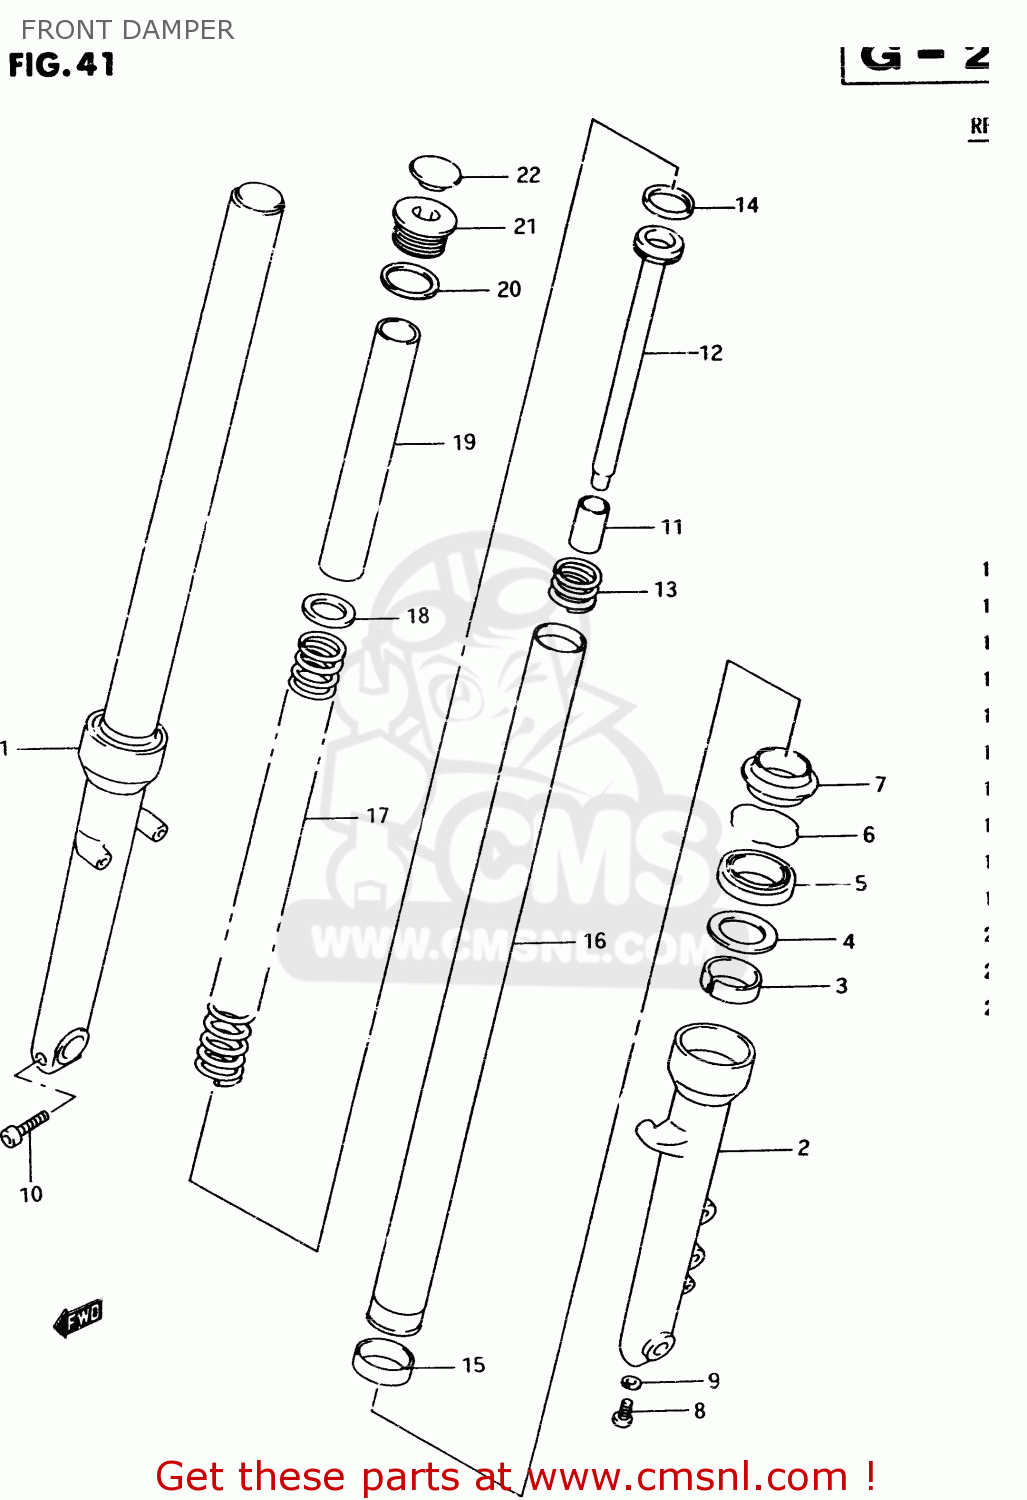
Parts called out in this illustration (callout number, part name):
1	TUBE,OUTER,R
2	TUBE,OUTER,L
3	BUSH,GUIDE
4	SPACER,SEAL
5	OIL SEAL,FRONT FORK
6	RING,STOPPER
7	SEAL,DUST
8	BOLT,CENTER (8X18)
9	GASKET (NAS)
10	BOLT
11	PIECE,OIL LOCK
12	CYLINDER
13	SPRING,REBOUND
14	RING,PISTON
15	BUSHING,SLIDE
16	TUBE,INNER
17	SPRING,MAIN
18	JOINT,SPRING
19	SPACER,SPRING
20	O RING
21	BOLT,FORK
22	CAP,FORK
